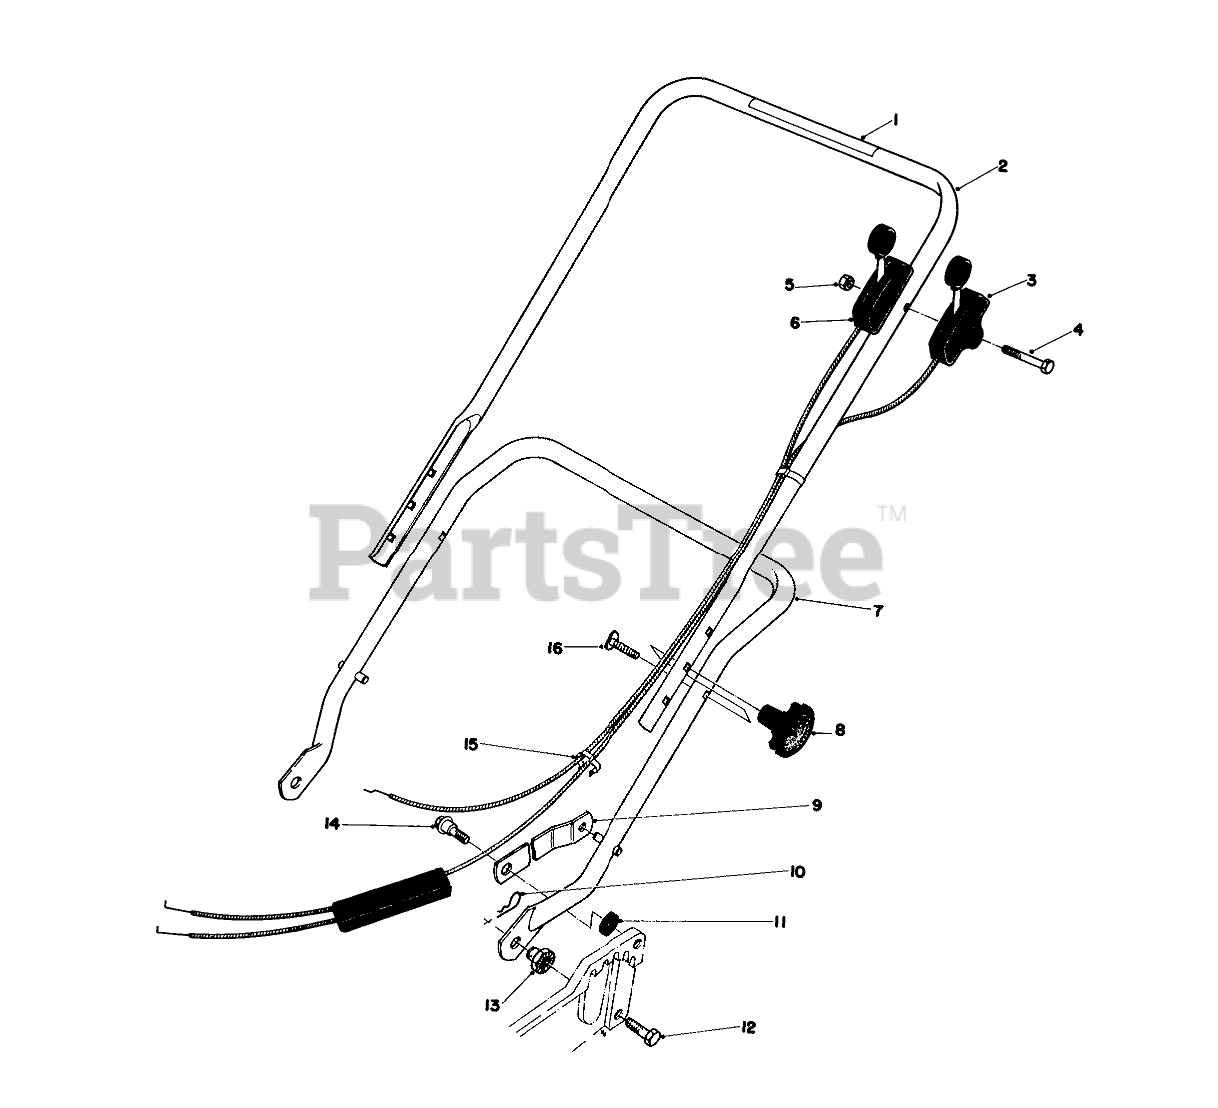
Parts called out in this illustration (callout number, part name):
1	Decal
2	Upper Handle
3	Traction Control
4	SCREW-HH
5	NUT-LOCK
6	Throttle Control
7	LOWER HANDLE ASM
9	HANDLE LATCH
10	PIN-COTTER, HAIR
11	SPACER
12	SCREW-HH
13	HANDLE PIVOT NUT
14	SCREW-SHOULDER
15	BOWDEN CLIP
16	SCREW-HANDLE
